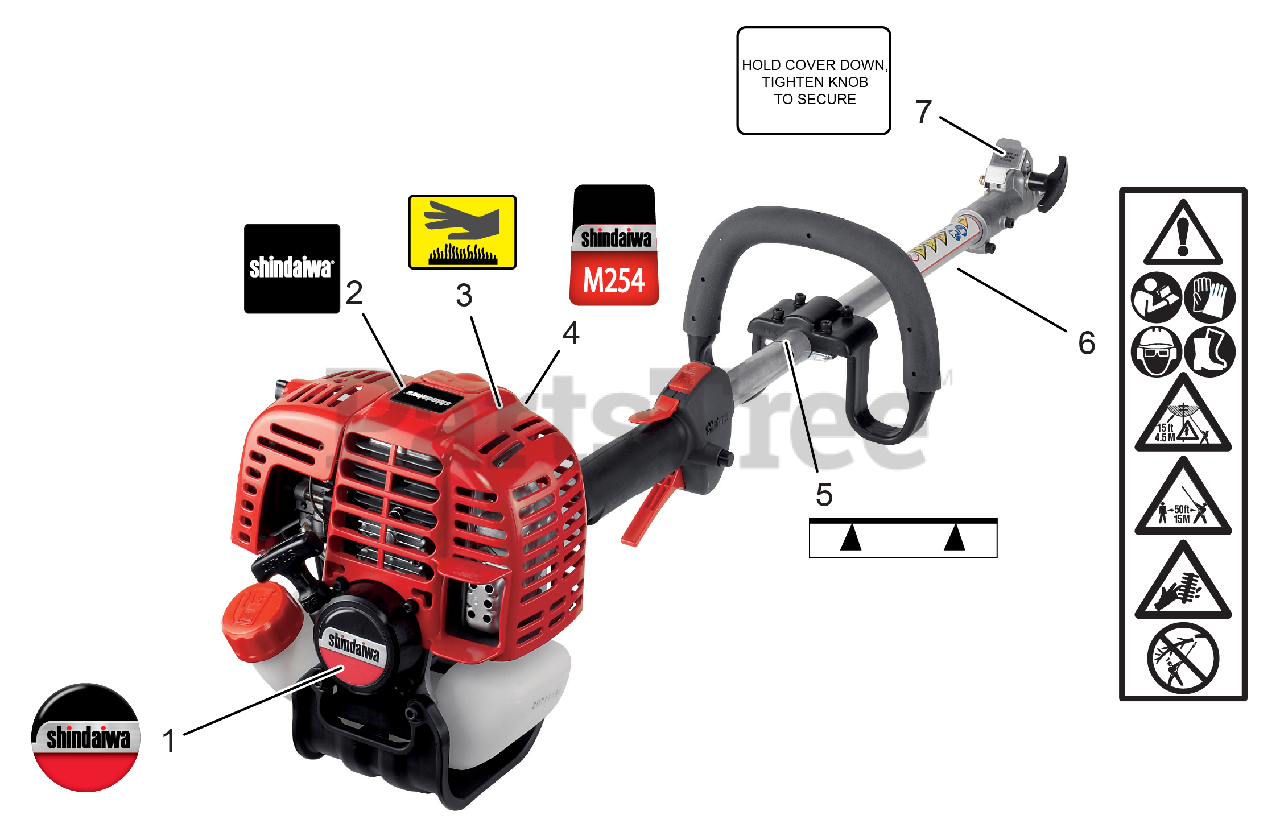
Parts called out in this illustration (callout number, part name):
1	LABEL - RECOIL STARTER
2	LABEL - SHINDAIWA
3	LABEL - CAUTION - HOT
4	LABEL - M254
5	LABEL - ALIGNMENT
6	LABEL - CAUTION
7	LABEL - LATCH INSTRUCTION
